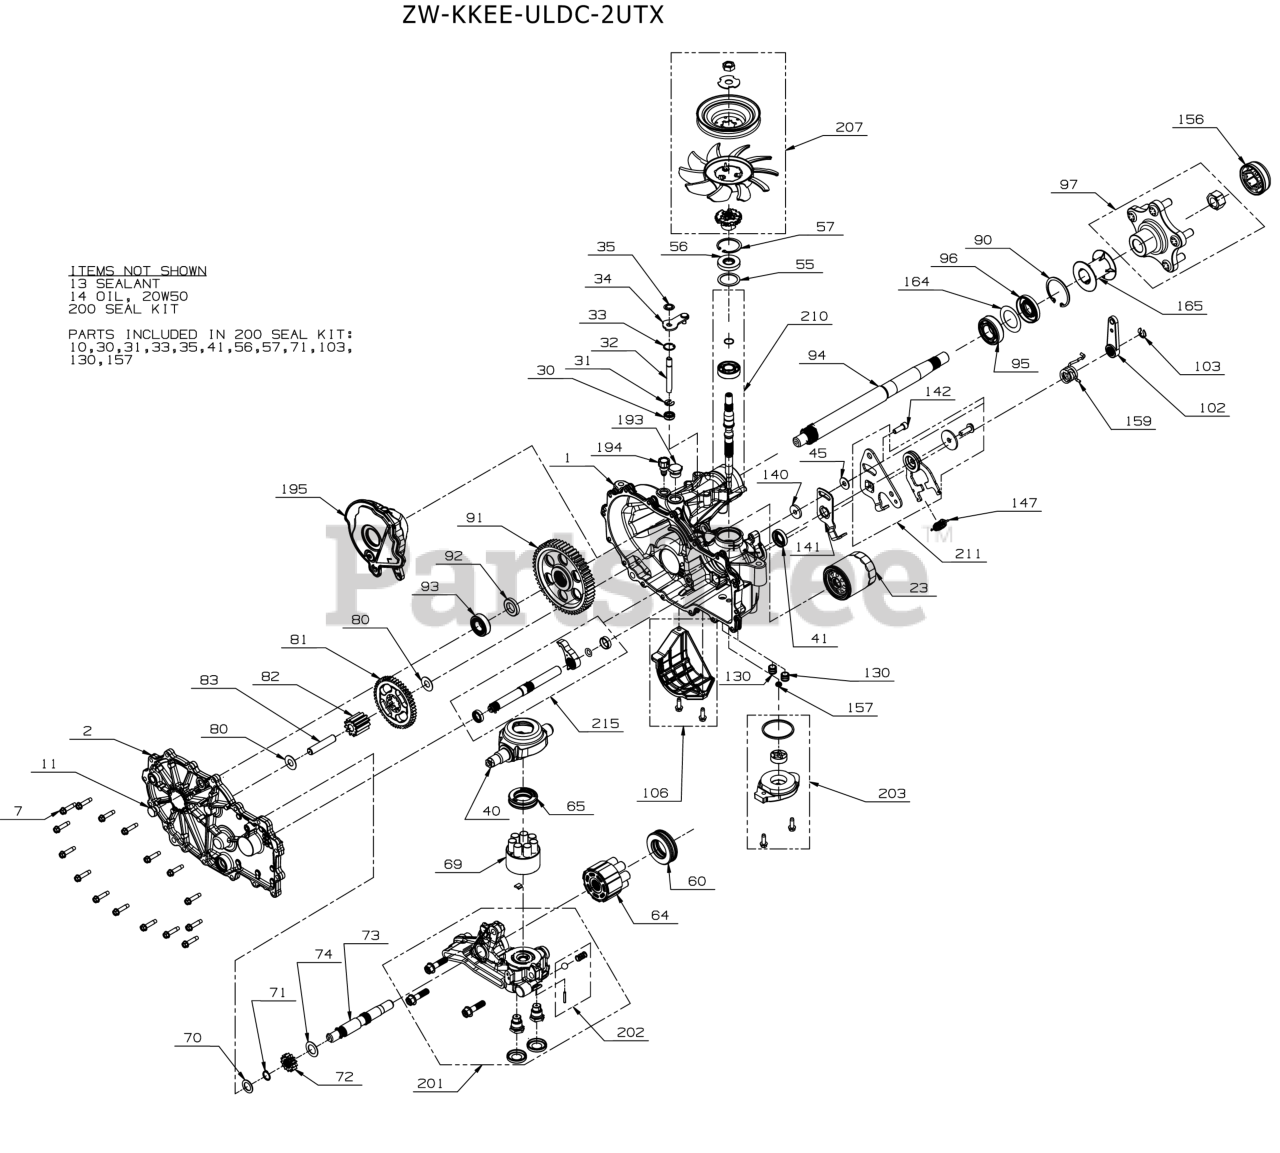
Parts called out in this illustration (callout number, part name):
1	MAIN HOUSING KIT (LH)
2	SIDE COVER KIT (LH)
7	SCREW-WASHER HEAD
11	VENT PLUG
13	SEALANT-HOUSING
23	OIL FILTER
30	SEAL-LIP .375 X .75 X .25
31	RETAINING RING
32	BYPASS RODS
33	RETAINING RING
34	ARM-BYPASS
35	RETAINING RING
40	SWASHPLATE-TRUNNION
45	FLAT WASHER
55	WASHER 1.23X1.56X
57	RETAINING RING
60	THRUST BEARING
64	CYLINDER BLOCK ASSEMBLY
65	THRUST BEARING
69	BLOCK KIT-CYLINDER
70	FLAT WASHER
71	RETAINING RING
72	GEAR - 13 TOOTH STEEL
73	MOTOR SHAFT
74	MOTOR SHAFT WASHER
81	GEAR - 46 TOOTH
82	GEAR-11 T
83	PIN-JACKSHAFT
90	RETAINING RING
91	GEAR - 54 TOOTH
92	SPACER .75X1.32X.257
93	BALL BEARING
94	AXLE SHAFT
95	BALL BEARING
97	5 BOLT HUB KIT
102	BRAKE LEVER
103	RETAINING RING
106	FILTER GUARD KIT
130	TUBE-CHARGE TRIPLE O-RING
140	SPACER .32 x 1.005 x .179
141	ARM-NEUTRAL (LH)
142	SCREWS KIT-RTN
147	EXTENSION SPRING
156	COVER-NUT
157	KIT-GEROTOR SEAL
159	TORSION SPRING CW
165	TUBE-AXLE 2.03
193	PLUG 3/4-16
194	BREATHER
195	EXPANSION TANK (LH)
201	CENTER SECTION KIT (LH)
202	KIT-CHARGE RELIEF
203	CHARGE KIT
207	FAN & PULLEY KIT
209	PULLER KIT-HUB
210	INPUT SHAFT KIT
211	RETURN KIT-NEUTRAL (LH) ZT2800 RZT
215	OUTPUT SHAFT KIT
